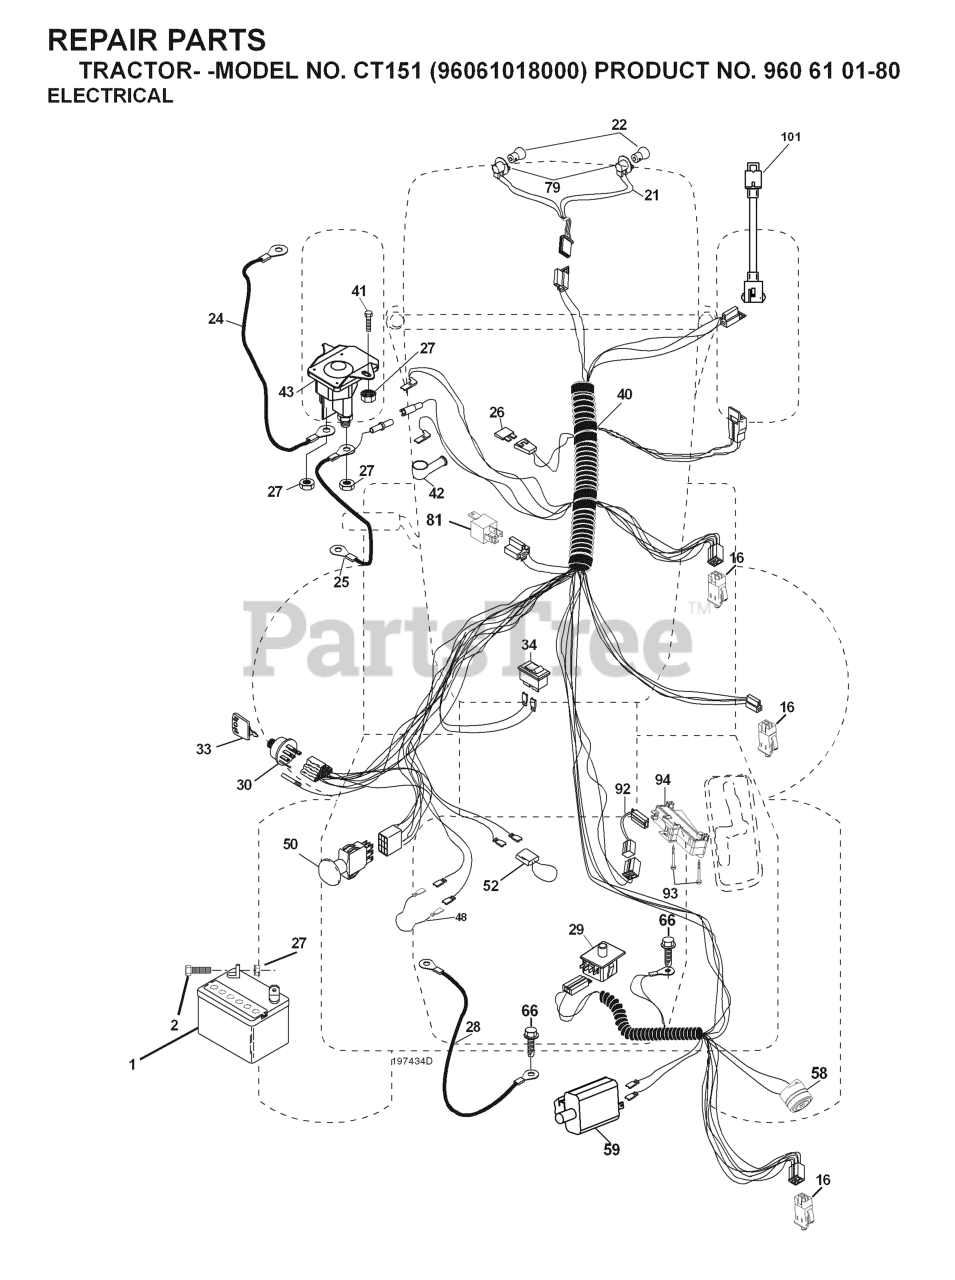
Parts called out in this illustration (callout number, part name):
1	BATTERY 12V .35 AMP
2	BOLT.HEX.1/4.X.3/4.DICHROMATE
16	SWITCH INTERLOOK PUSH-IN
21	HARNESS.LIGHT W/4152J BULBS
24	BATTERY CABLE GT
25	CABLE BATTERY
26	FUSE 20AMP
27	NUT
28	CABLE GROUND
29	SWITCH.SEAT.DP W/RAMPS
30	SWITCH.IGN.DELTA.W.LGH.ROS
33	KEY MLD GEN DELTA
40	RP HARNESS.IGN.ELECT.REG.CRD
41	BOLT
42	TERMINAL COVER
43	SOLENOID.W/BRASS.PLUNGER
48	ADAPTER.AMMETER
50	RP.PTO.SWITCH.8 TERMINAL.BLACK
52	WIRE PROTECTION LOOP
58	BUZZER
59	.WITCH.FULL BAGGER.INDICATOR
79	BULB HOLDER ASM.
81	RELAY.ASSY.T
92	HARNESS.PIGTAIL.CONSLE
93	SCREW.PLASTITE
94	MODULE.REVERSE.ROS
101	PIGTAIL.MATNLK.NEW.HAR
